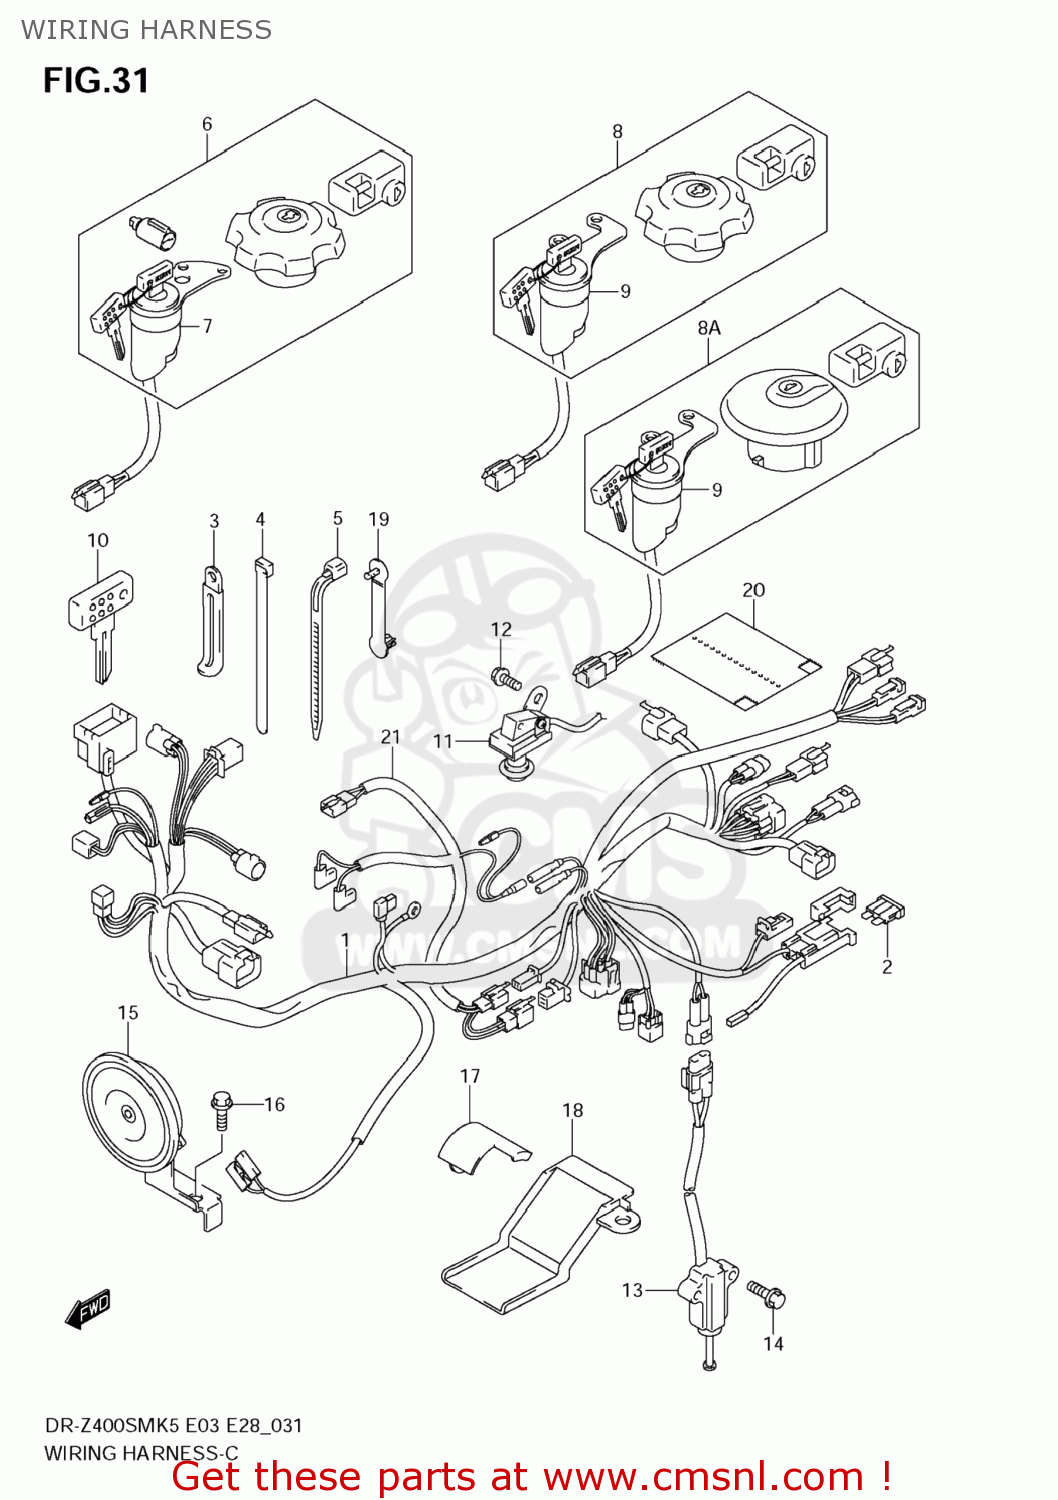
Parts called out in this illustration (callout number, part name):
1	HARNESS,WIRING
2	FUSE(20A)
3	CLAMP(L:45)
4	CLAMP(L:145)
5	CLAMP(L:125)
6	LOCK SET
7	SWITCH ASSY,IGNITION
8	LOCK SET
8A	LOCK SET
9	SWITCH ASSY,IGNITION
10	KEY,BLANK(TYPE:C)
11	SWITCH ASSY
12	SCREW
13	SWITCH ASSY,SIDE STAND
14	BOLT
15	HORN ASSEMBLY
16	BOLT
17	PROTECTOR,WIRING HARNESS
18	PROTECTOR,WIRING HARNESS
19	CLAMP(L:63)
20	COVER,WIRING HARNESS
21	WIRE,CARB HEATER
